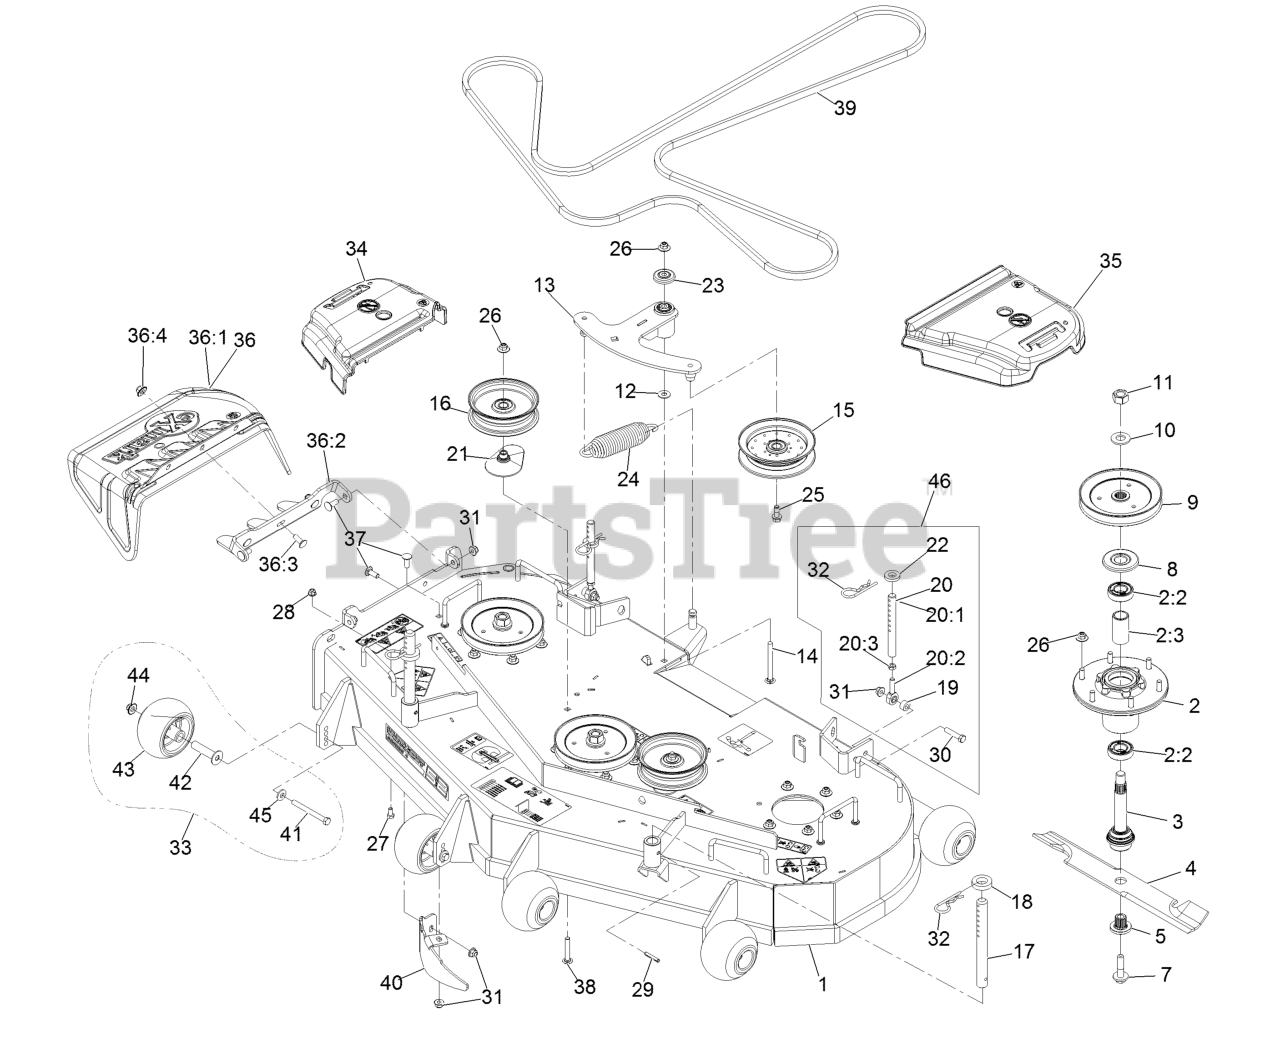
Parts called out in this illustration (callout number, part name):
1	ASM, Deck W/ Decals, 52"
2	ASM-Cutter Hsg With Bearings
2:2	Bearing-Ball
2:3	Spacer-Bearing
3	ASM-Spindle And Seal
4	Blade, Solid
4	Blade, Low Lift
4	Blade, Mulching
4	Blade-Notched
4	Blade-Extreme 2, 18.00"
5	Bushing, Splined
7	Screw-Sems 1/2-20 X 2.19
8	Guard,Bearing Top .989
9	Sheave,Blade Drive 6.50
10	Washer-Spring Disc 3/4
11	Nut-Hex
12	Washer-3/8 Std
13	ASM, Deck Idler
14	Bolt-Carriage 3/8-16 X 3 3/4
15	Idler-Pulley, Flanged
16	Idler-Pulley, Flat
17	Rod, Deck Support
18	Spacer-Deck Support
20	Link Assy
20:1	Link, Rear Deck Support
20:2	Balljoint
20:3	Nut-Jam 3/8-24
21	Spacer-Pulley
22	Spacer-Blade Drive
23	Guard-Top
24	Spring-Extension
25	Screw-Hfh
26	Nut-Nyloc 3/8-16 Flg
27	Screw-HH 5/16-18 X 5/8
28	Nut-Nyloc 5/16-18 Flg
29	Rollpin 1/4 X 1 1/2
30	Screw-HH 3/8-16 X 1 3/4
31	Nut-Nyloc 3/8-16 Flg
32	Hairpin-Cotter #206
33	Kit, Anti-Scalp Roller
34	Cover-Belt, RH
35	Cover-Belt, LH
36	ASM,Discharge Chute
36:1	Chute, Discharge
36:2	Bracket,Discharge Chute
36:3	Bolt-Carriage 3/8-16 X 1
36:4	Nut-Nyloc 3/8-16 Flg
37	Bolt-Carriage 3/8-16 X 1
38	Bolt-Carriage 3/8-16 X 2 1/4
39	Belt, Deck Drive
40	Baffle-Dogleg, Lz-Vt52
41	Screw-HH 3/8-16 X 3 3/4 GR 8
42	Axle, Roller
43	Roller-Anti-Scalp
44	Nut-Nyloc 3/8-16 Flg
45	Washer-Spring Disc 3/8
46	Kit, Support Link W/Pin
